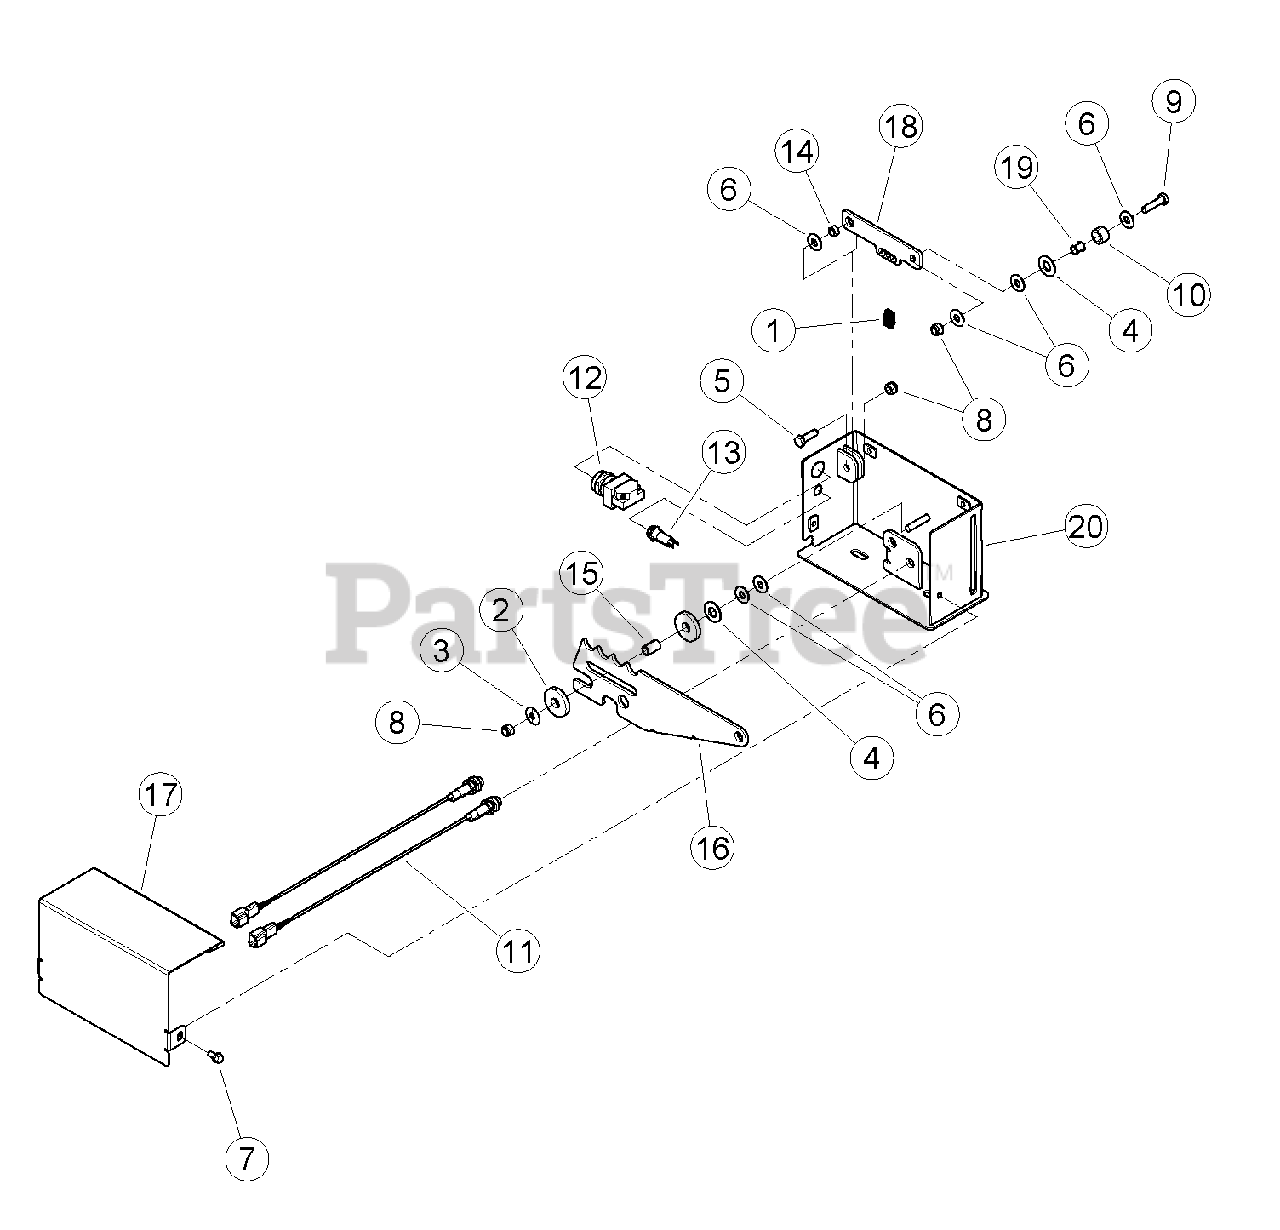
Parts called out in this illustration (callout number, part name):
1	SPRING, CONTROL BAR
2	WASHER, UHMW SPACER .515ID X 1.50OD
3	WASHER, SPRING
4	WASHER, 1/2 SAE FLAT ZP
5	BOLT, 5/16 X 1 HEX GR5 NC ZP
6	WASHER, 5/16 FLAT ZP
7	BOLT, 1/4 X 1/2 SERRATED FLANGE GR5 ZP
8	NUT, 5/16 NE NYLOCK ZP
9	BOLT, 5/16 X 1-1/4 HEX GR5 NC ZP
10	ROLLER, NYLON .75OD X .502ID X .440
11	SENSOR, M12 PNP PROXIMITY (REPLACEMENT PART)
12	SWITCH, MOMENTARY IP67 NORMALLY OFF
13	LED, TRI-COLOR 12V 3-TERMINAL BASE
14	SPACER, IDLER PIVOT
15	SPACER, .50 X .775
16	BAR, SWITCH CONTROL
17	COVER, CONTROL BOX
18	LINK, DETENT
19	SPACER, 1/2 OD X .35 ID X .47
20	WELDMENT, SWITCH BOX
